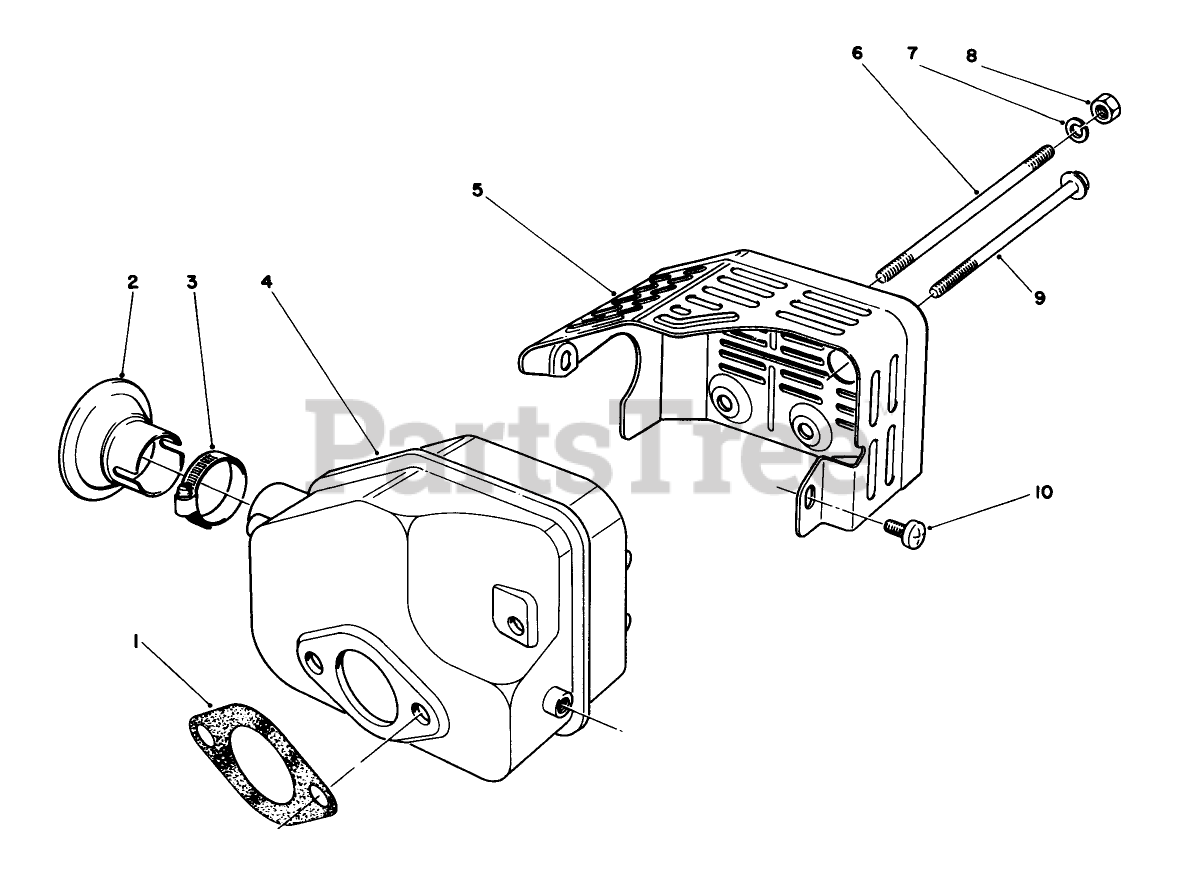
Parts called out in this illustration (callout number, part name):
1	GASKET
3	Clamp
4	MUFFLER
5	COVER-MUFFLER
7	WASHER-LOCK
10	SCREW
